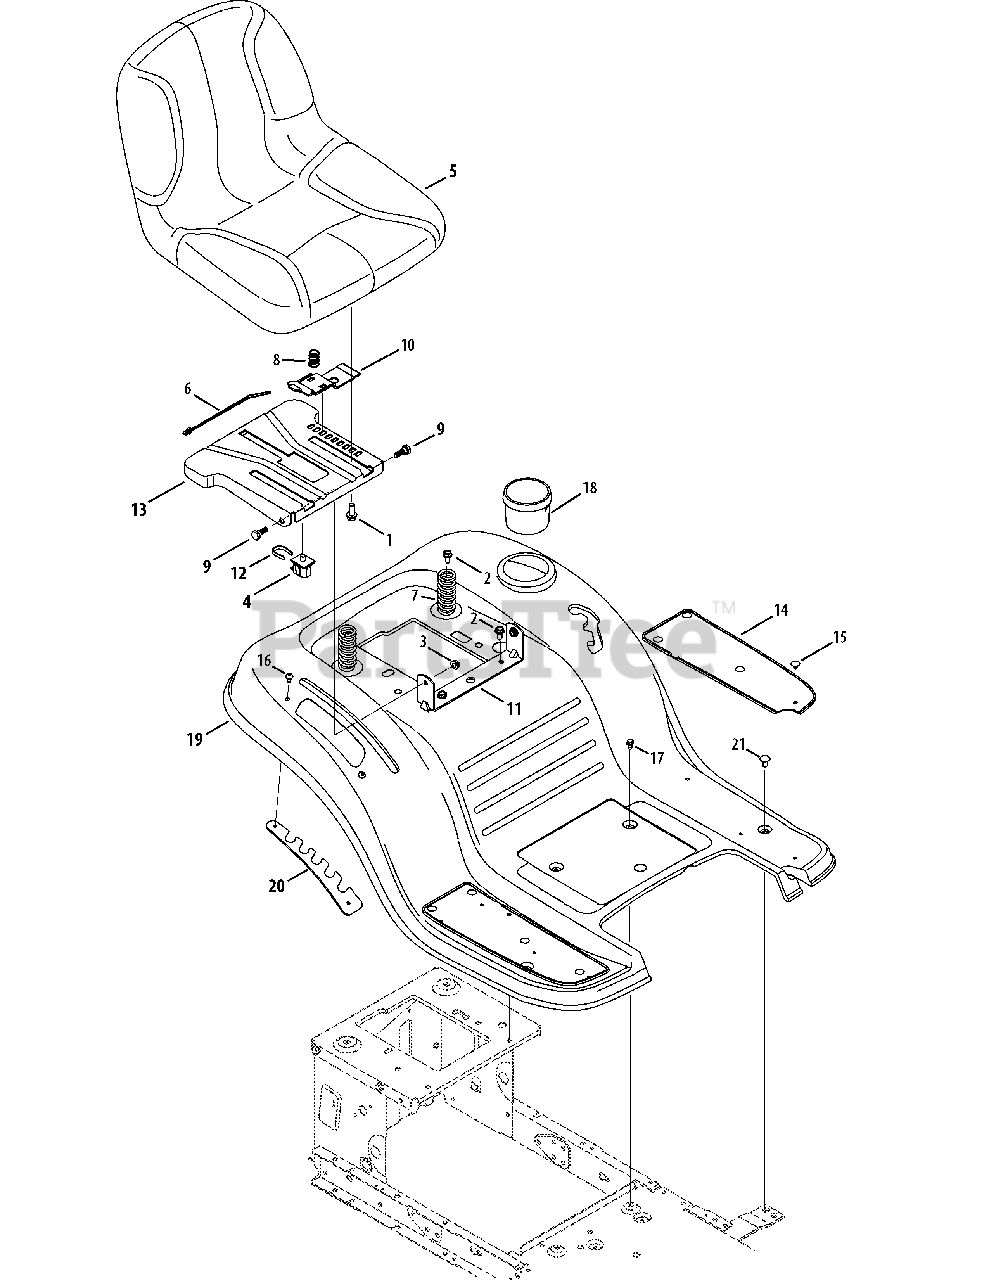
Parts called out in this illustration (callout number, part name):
1	Hex Flange Bolt, 3/8-16 x .875
2	Screw, Hd. Tapp, 5/16-18 x .75
3	Flange Lock Nut, 5/16-18
4	Seat Safety Switch
5	Seat
6	Push Mount Cable Tie
7	Spring, Compress., 1.28 x 3.125
8	Spring, Compress., .68 x 1.065 x .055
9	Shoulder Screw, 5/16-18 x .437 x .268
10	Seat Adjustment Lever
11	Seat Pivot Bracket
12	Switch Retainer Clip
13	Seat Mounting Bracket
14	Rubber Foot Pad, LH
14	Rubber Foot Pad, RH
15	Ratchet Clip, .250
16	Tap Screw, 1/4-20 x .5
17	Screw Pan Torx Head, 1/4-20 x .500
18	Cup Holder
19	Fender
20	Lift Adjuster Bracket
21	Carriage Screw, 1/4-20 x .62
